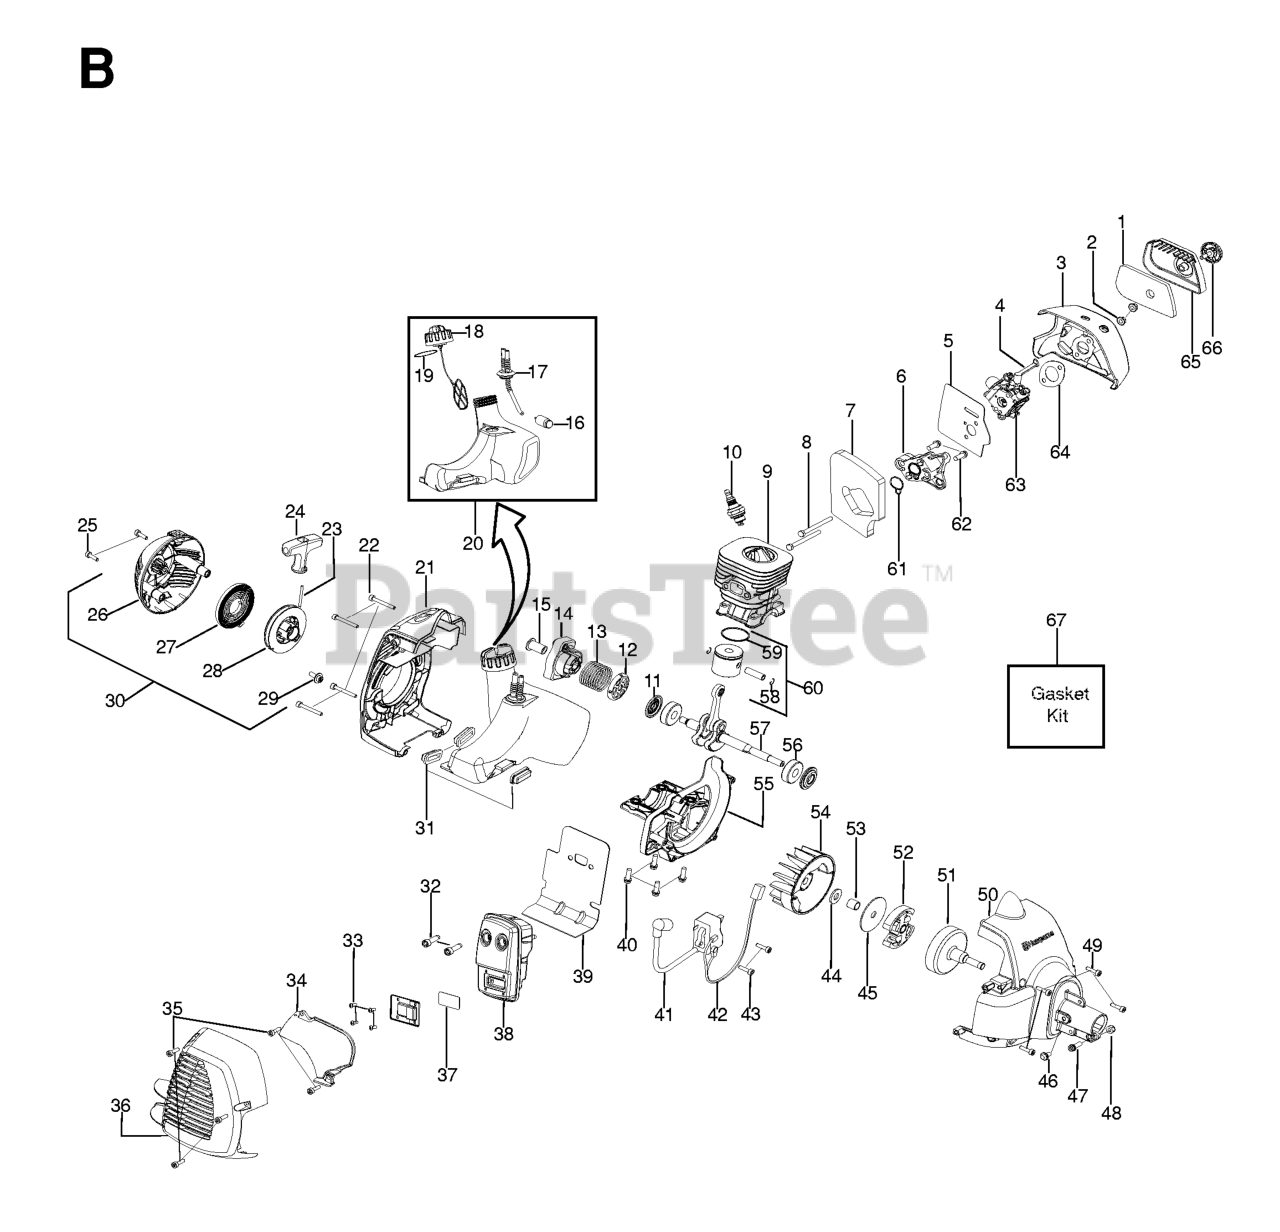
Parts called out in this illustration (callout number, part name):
1	FILTER AIRBOX
3	AIRBOX
4	CHOKE LEVER
5	KIT GASKET CARB
6	CARB ADAPTOR
7	KIT GASKET 28CC TRIMMER
8	BOLT CARB ADAPTOR
9	CYLINDER
10	Plug - Spark (RCJ-8Y)
11	KIT SEAL CRANKSHAFT
12	WASHER STARTER
13	SPRING STARTER CUP
14	ASSY STARTER CUP
15	COUPLING STARTER
16	FUEL PICK-UP ASSY
17	KIT FUEL LINE
18	ASSY-CAP W/RETAINER
19	O RING NITRILE
20	ASSY FUEL TANK
21	REAR SHROUD
24	STARTER HANDLE GRAY
25	SCREW M5-0.8X30MM
26	STARTER HOUSING
27	%KIT STARTER SPRING
28	KIT STARTER PULLEY
30	STARTER HOUSING ASSY
31	ISOLATOR FUEL TANK
32	BOLT MUFFLER
33	SCREW-10-16 X 1/2 HI-LO
34	SHIELD HEAT
35	SCREW M4 X 1.75 PT 16MM
36	MUFFLER GUARD
37	KIT SPARK ARRESTOR SCREEN
38	ASSY MUFFLER
39	GASKET PAPER METAL
40	SCREW-M5-0.8 X 25MM(TAP)
41	IGNITION MODULE MBU-7
42	ASSY MODULE LEAD WIRE
43	SCREW M4 X .70 TT 16MM
45	WASHER-CLUTCH
48	NUT HEX LOCK 10-24
49	SCREW M4 X .70 TT 16MM
50	FAN HSG ASSY
51	ASSY-CLUTCH DRUM
52	%KIT CLUTCH ASSY
53	SPACER FLYWHEEL
55	CRANKCASE CASTING
56	BEARING RADIAL BALL (6201)
57	KIT CRANKSHAFT ASSY
58	WRIST PIN RET.
59	RING PISTON
60	KIT PISTON 28CC TRIMMER
61	KIT GASKET 28CC TRIMMER
62	SCREW-M5-0.8 X 25MM(TAP)
63	KIT CARBURETOR
64	KIT GASKET 28CC TRIMMER
65	COVER-AIR BOX
66	KNOB ASSY AIRBOX COVER
67	KIT GASKET 28CC TRIMMER
530058709	PURGE BULB ZAMA
